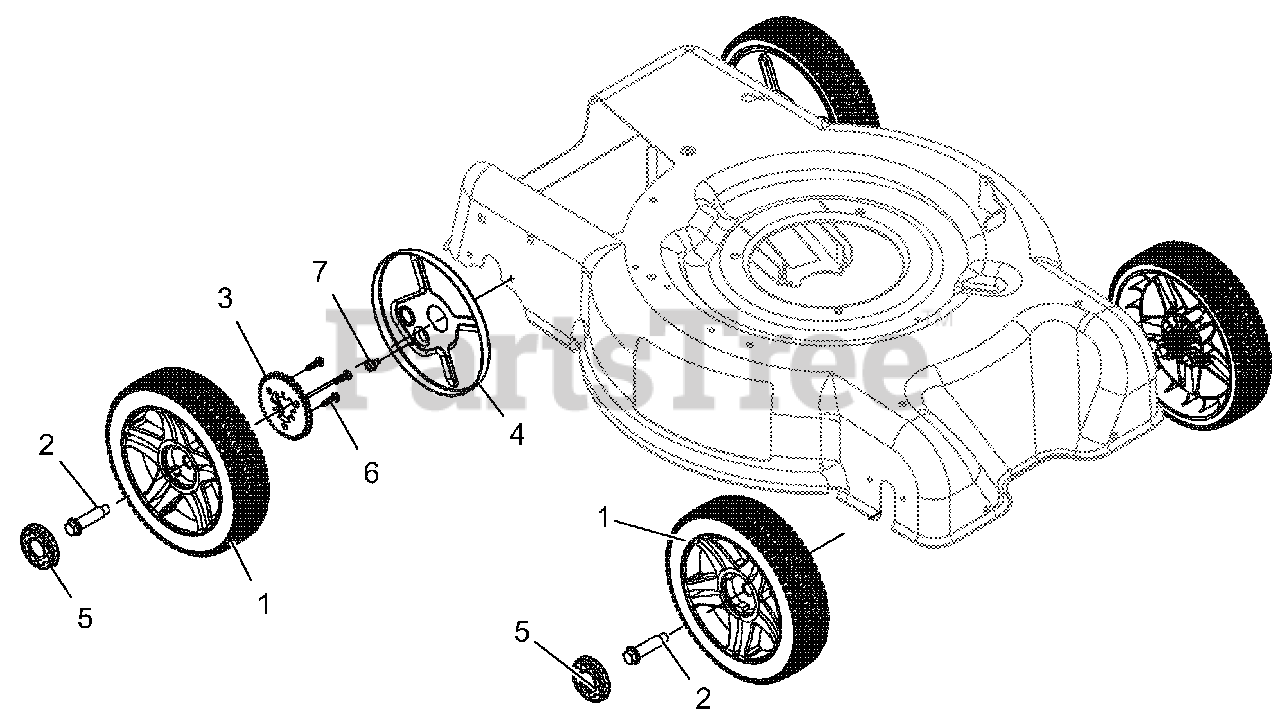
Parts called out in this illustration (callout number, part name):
1	WHEEL, LM - XD3
2	BOLT, SHLDR
3	GEAR, WHEEL
4	COVER, WHEEL
5	CAP, LM WHEEL HUB- GRAVELY
6	SCR-TAP #12-14 x .75 PLASTITE BLZC
7	SCR-TAP .25-20 x .37 HWH YWZ TR
